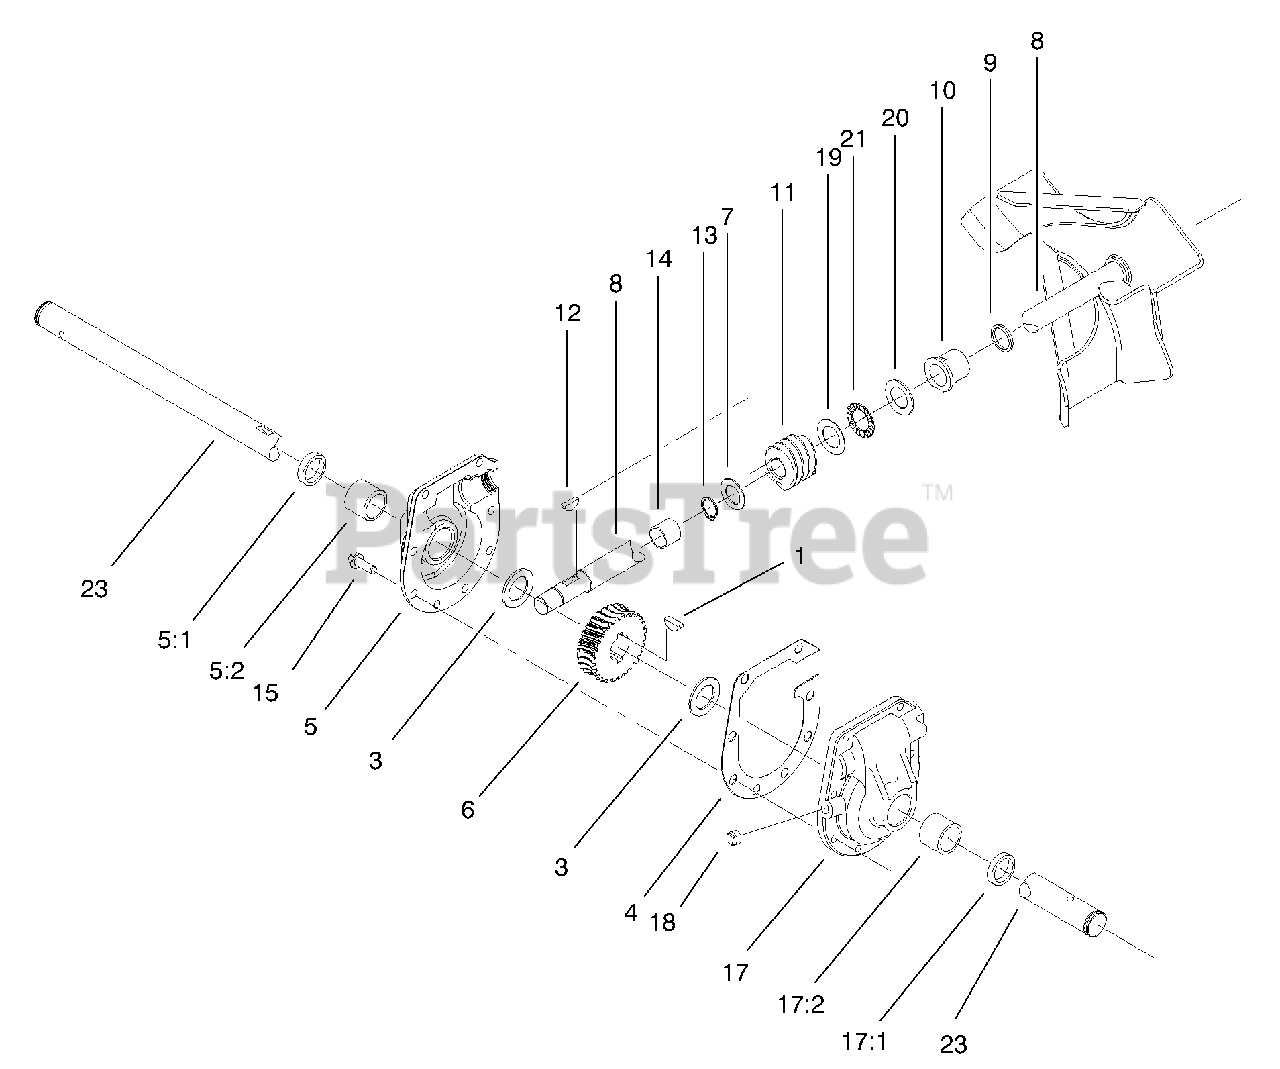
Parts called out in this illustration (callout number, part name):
1	Key-Woodruff
3	Washer-Thrust
4	Gasket-Gear Box
5	Case-RH Gear
5:1	Seal-Oil
6	Gear-Worm 27t
7	Washer-Thrust
9	Ring-Quad
10	Bushing-Input
12	Key-Woodruff
13	Ring-Snap
14	Bushing
15	Screw-Taptite
17	Case-LH Gear
17:1	Seal-Oil
18	Plug-Pipe, SQH
19	Washer-Thrust
20	Washer-Thrust
21	Bearing-Thrust
23	Shaft-Auger
24	Seal-Oil
